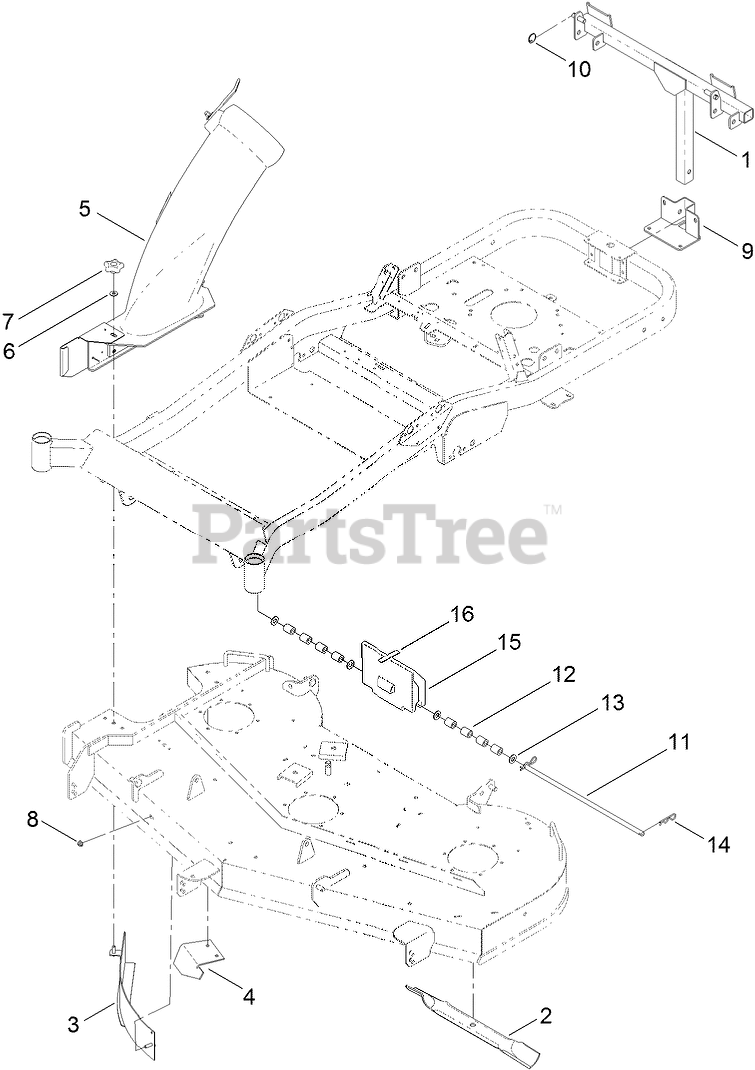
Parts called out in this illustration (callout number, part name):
1	FRAME-PIVOT
2	BLADE-20.50 INCH
3	BAFFLE-BAGGER
4	BAFFLE-CUTOFF
5	BAGGER BOOT ASM
6	WASHER-FLAT
7	KNOB-LOCKING
8	NUT-HF, NI
9	SUPPORT-BAGGER
10	PIN-COTTER, CIRCULAR
11	ROD-DECK, PIVOT
12	SPACER-WHEEL
13	WASHER-FLAT
14	PIN-HAIR
15	WEIGHT-BAGGER
16	BUMPER-PAD
